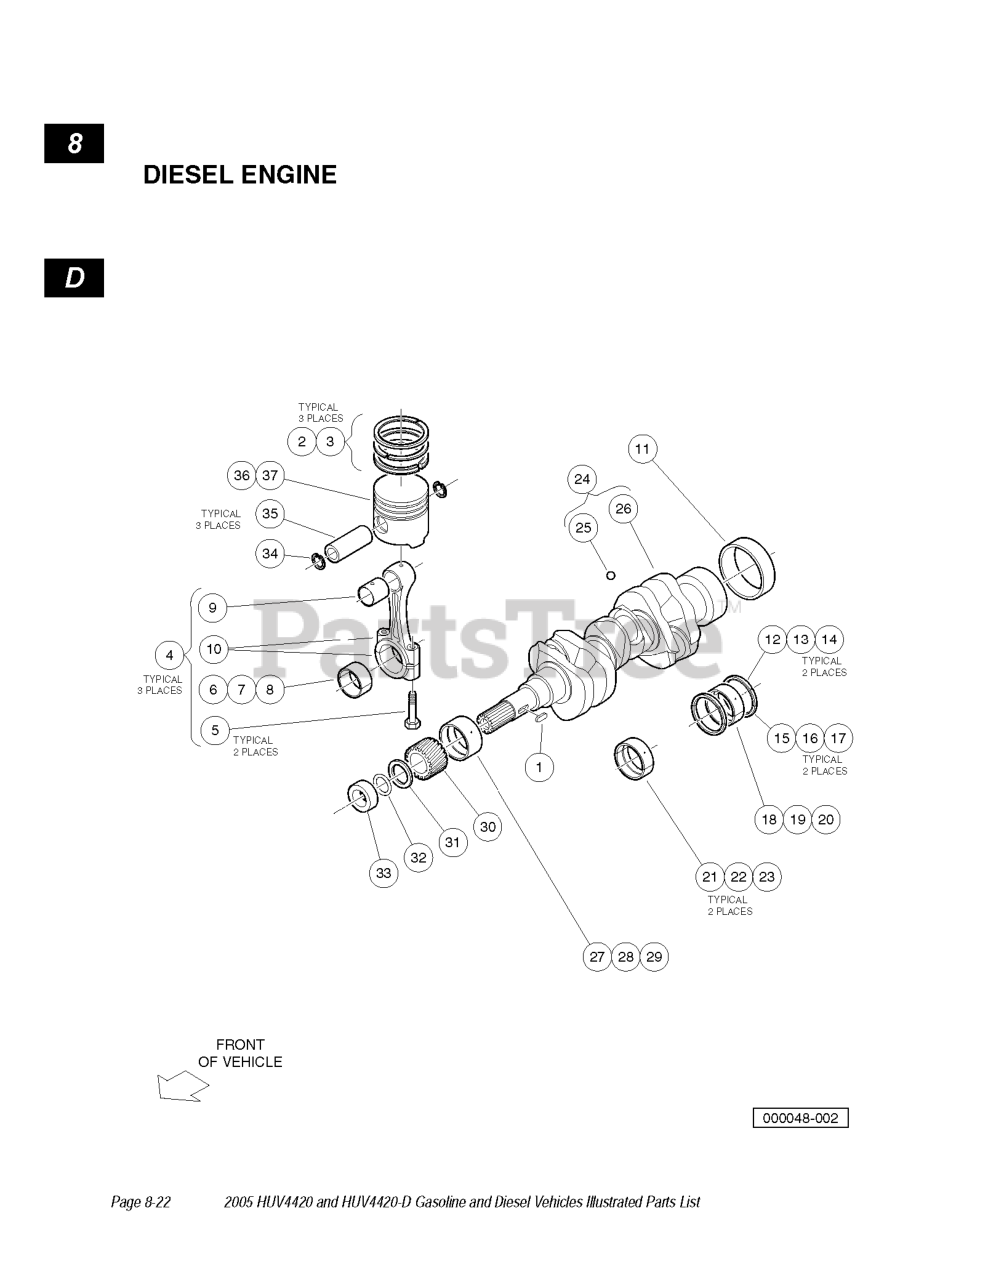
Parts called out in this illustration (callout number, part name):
1	KEY, FEATHER, SHORT CAMSHAFT
2	ASSY PISTON RING, D722 STD
3	ASSY PISTON RING, D722 + .025
4	ASSY, CONNECTING ROD
5	BOLT, CONNECTING ROD
6	METAL, CRANK, ROD, D722, STD
7	METAL, CRANK, ROD, D722, .020
8	METAL, CRANK, ROD, D722, .040
9	BUSHING, PISTON PIN, D722
11	SLEEVE, CRANKSHAFT
12	METAL, CRANK, 0 SIDE, STD
13	METAL, CRANK, 0 SIDE + .020
14	METAL, CRANK, 0 SIDE, +.040
15	METAL, CRANK, 1 SIDE, STD
16	METAL, CRANK, 1 SIDE, +.020
17	METAL, CRANK, I SIDE, +.040
18	METAL, CRANK, MAIN, REAR STD
19	METAL, CRANK, MAIN, REAR-.020
20	METAL, CRANK, MAIN, REAR-.040
21	METAL, CRANK, MAIN, MID STD
22	METAL, CRANK, MAIN, MID+.020
23	METAL, CRANK, MAIN, MID+.040
24	COMP, CRANKSHAFT
25	BALL, CRANKSHAFT
27	METAL, CRANK, D722, FRNT, STD
28	METAL, CRANK, 722, FRNT, -.020
29	METAL, CRANK, 722, FRNT, -.040
30	GEAR, CRANK
31	SLINGER, OIL
32	O RING, 23X26
33	COLLAR, CRANKSHAFT
34	CIRCLIP, PISTON PIN
35	PIN, PISTON
36	PISTON, D722, STD
37	PISTON, D722, +0.25
